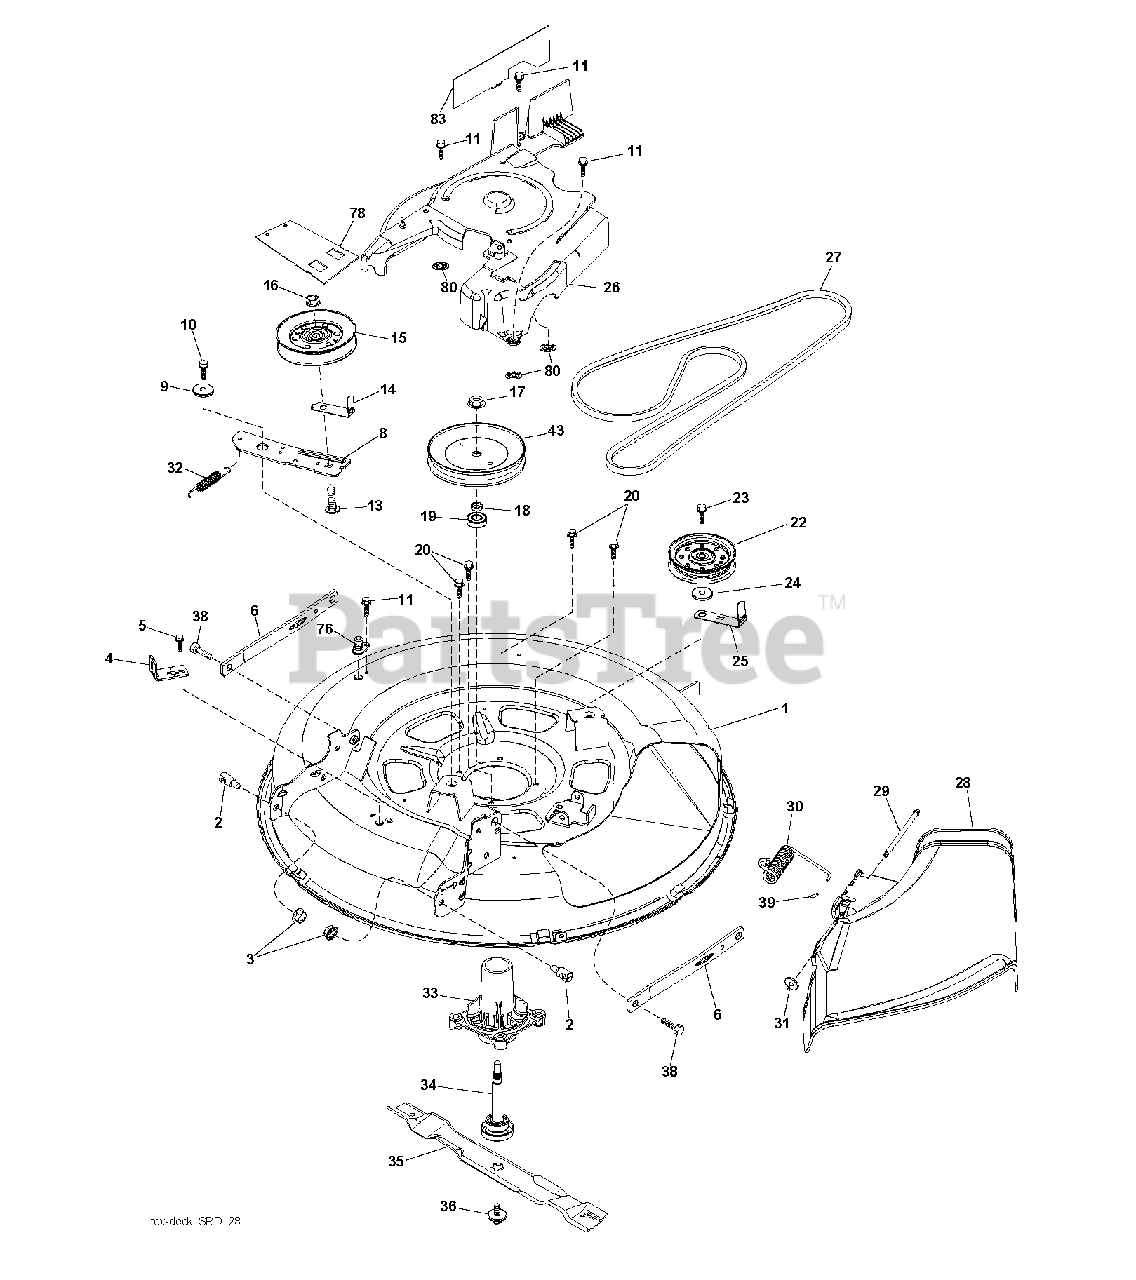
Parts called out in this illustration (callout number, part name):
2	STUD.FASTNER.W/ANTI-ROTATE
3	NUT LOCK HEX FLANGE 5/16-18
5	BOLT.5/16HEX.WHS.HD
6	ARMS.SUSP.MOWER.REAR.SRD
9	SPACER.RETAINER
10	SCREW 3/8-16X1
11	SCREW.1/4-20X5/8
13	BOLT.3/8-16X1.50
14	KEEPER, BELT IDLER
15	PULLEY.IDLER.4.25
16	NUT LOCK FLG 3/8-16 UNC
17	NUT.FLANGE.LOCK.TOP
18	WASHER.SPACER.MANDREL
20	SCREW, WASHER HEAD
22	PULLEY.IDLER.FLAT.UNPLATED
23	SCREW LT
27	V-BELT.DRIVE.MOWER.30"
28	SHIELD.DEFLECT.MWR.30S.BLACK
30	SPRING.TORSION.DEFLECT
31	NUT PUSH M
32	SPRING.MOWER.DRIVE.ELECTRIC
33	HOUSING MANDREL
34	SHAFT.ASM.MDRL.N/GREASE.38
35	BLADE.MOWER.BAGGING.30"
36	BOLT.WASHER.ASM.7/16-2
38	BOLT.SHOULDER
39	CAP-SLEEVE LT
43	PULLEY, MANDREL 6.5 PD
76	PORT.WASHOUT
80	PALNUT 1/4
